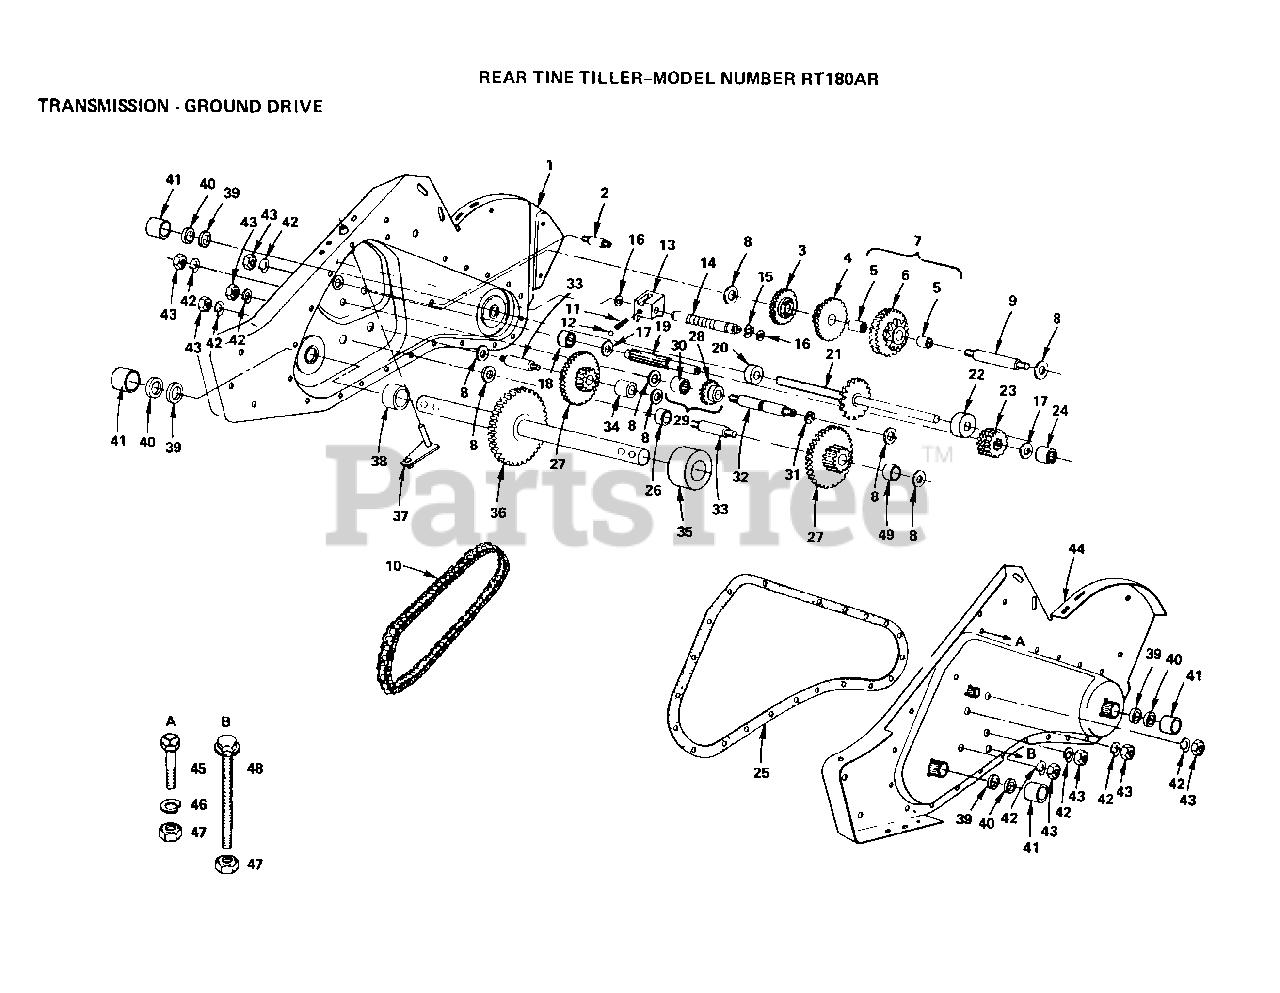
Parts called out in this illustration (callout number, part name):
2	BOLT TI
3	REVERSE GEAR TI
4	CLUSTER GEAR TI
5	"CRT, BEARING"
7	SPROCKET ASSY TI
8	WASHER
9	REDUCTION SHFT TI
10	CHAIN TI
11	SPRING-SHIFT CRT
13	SHIFT FORK TI
14	SHIFT SHAFT TI
15	KLIP RING
17	"T, BEARING"
18	"TI, BEARING"
19	SHAFT INPUT T
23	INPUT PINION TI
24	NEEDLE BRNG LT
25	GEARCASE GSKT TI
27	GEAR CLUSTER CRT
28	REVERSE GEAR TI
29	GEAR ASSY TI
30	NEEDLE BEARING TI
31	KLIP RING
32	REVERSE SHAFT TI
33	SHAFT CRT
36	SHAFT ASSY CRT
41	CUP.FORMED.
42	LOCKWASHER
43	NUT.ASF.HEX.7/16
45	BOLT
46	LOCKWASHER
47	NUT.HEX.5/16-18
48	BOLT TI
